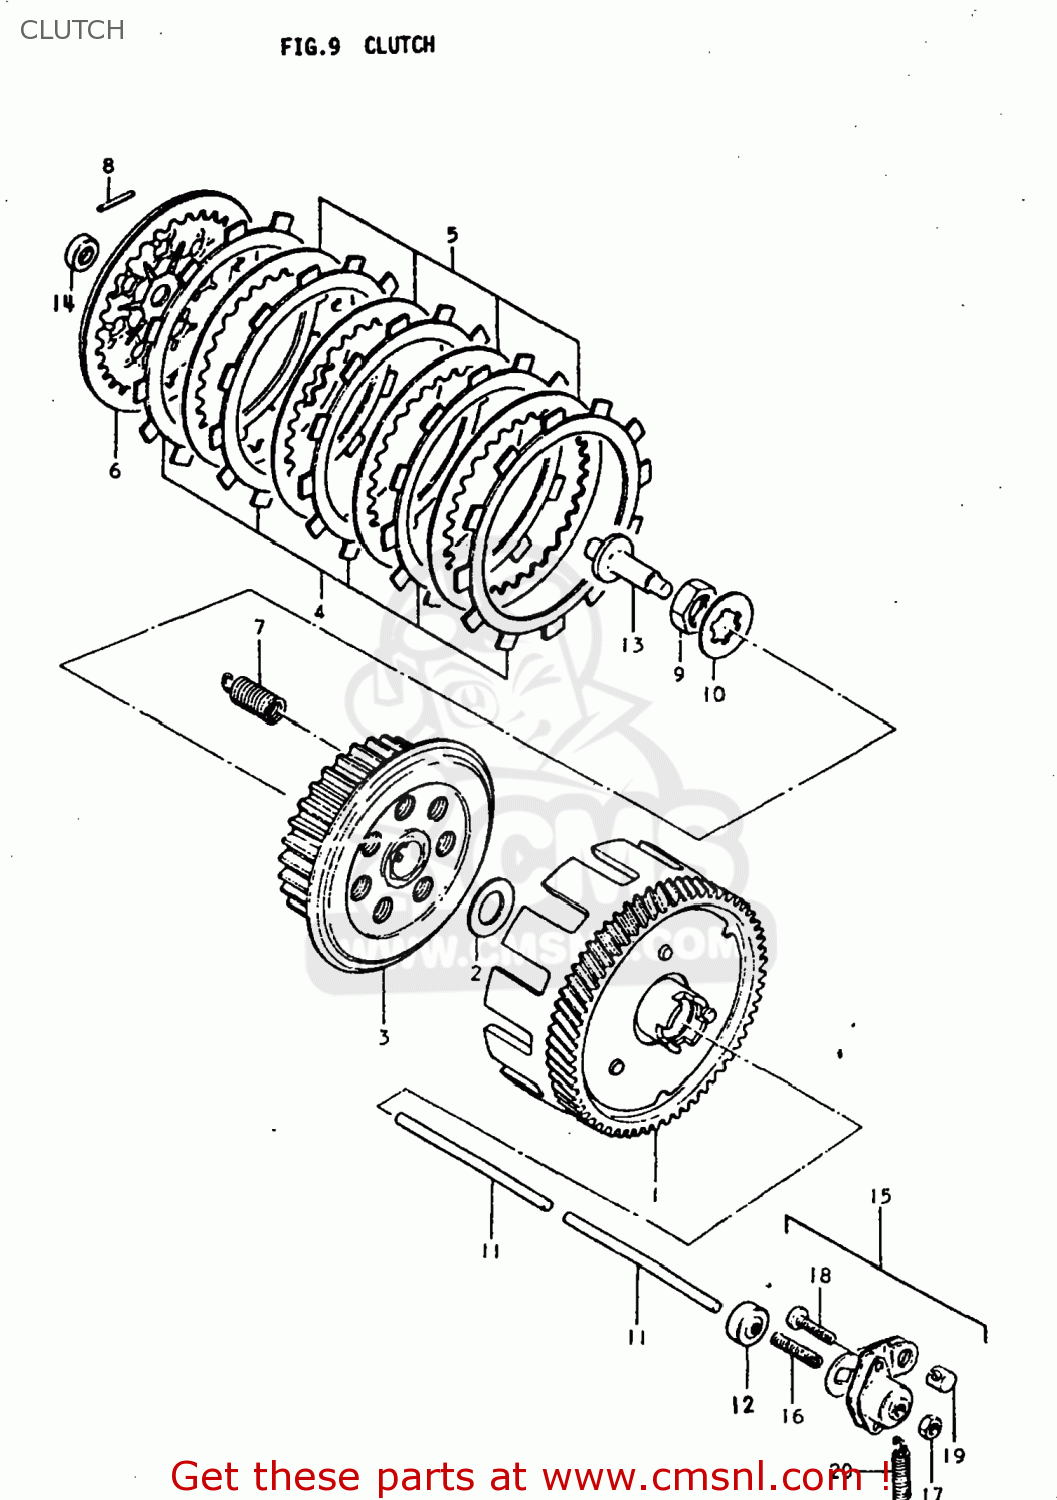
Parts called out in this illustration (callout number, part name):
1	GEAR ASSEMBLY,PRIMARY DRIVE
2	WASHER
3	HUB,CLUTCH SLEEVE
4	PLATE,CLUTCH DRIVE
5	PLATE,CLUTCH DRIVEN (NAS)
6	PLATE,CLUTCH PRESSURE
7	SPRING
8	PIN(2.5X19.8)
9	NUT
10	WASHER,LOCK
11	ROD,CLUTCH PUSH
12	OIL SEAL
13	ROD,CLUTCH RELEASE
14	SEAL,OIL (10X17X5)
15	SCREW ASSEMBLY,CLUTCH RELEASE
16	SCREW
17	NUT
18	SCREW
19	PIECE,RELEASE ARM END
20	SPRING
